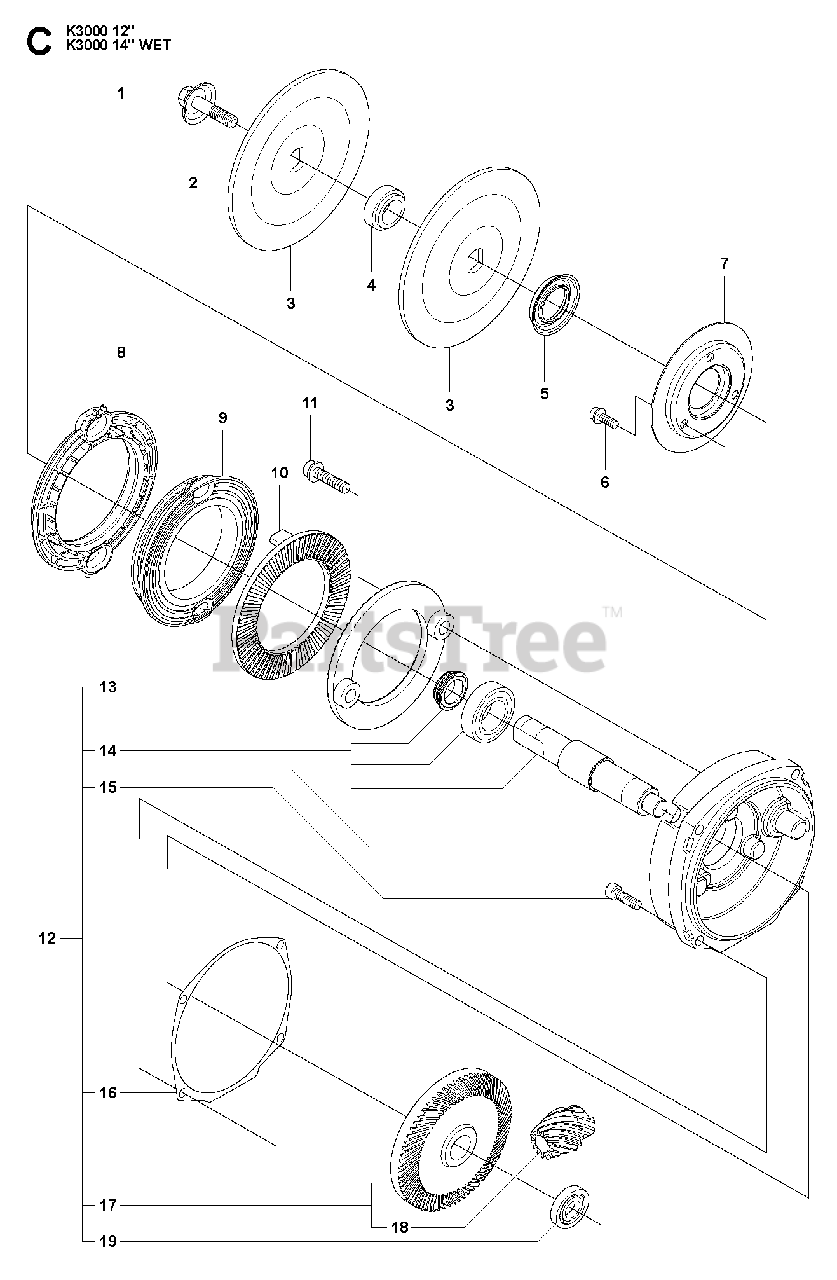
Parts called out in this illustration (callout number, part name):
3	FLANGE WASHER
4	KITDiam 20mm
4	KITDiam 22,2mm
4	KITDiam 25,4mm
4	BUSHINGDiam 30,5mm
8	SPACER RING"12"" only"
11	SCREW IHSCFM
12	GEAR SETIncl. 13 - 17, 19
14	SHAFT
15	SCREW
16	GASKET
17	GEAR WHEELIncl. 18
19	BALL BEARING
